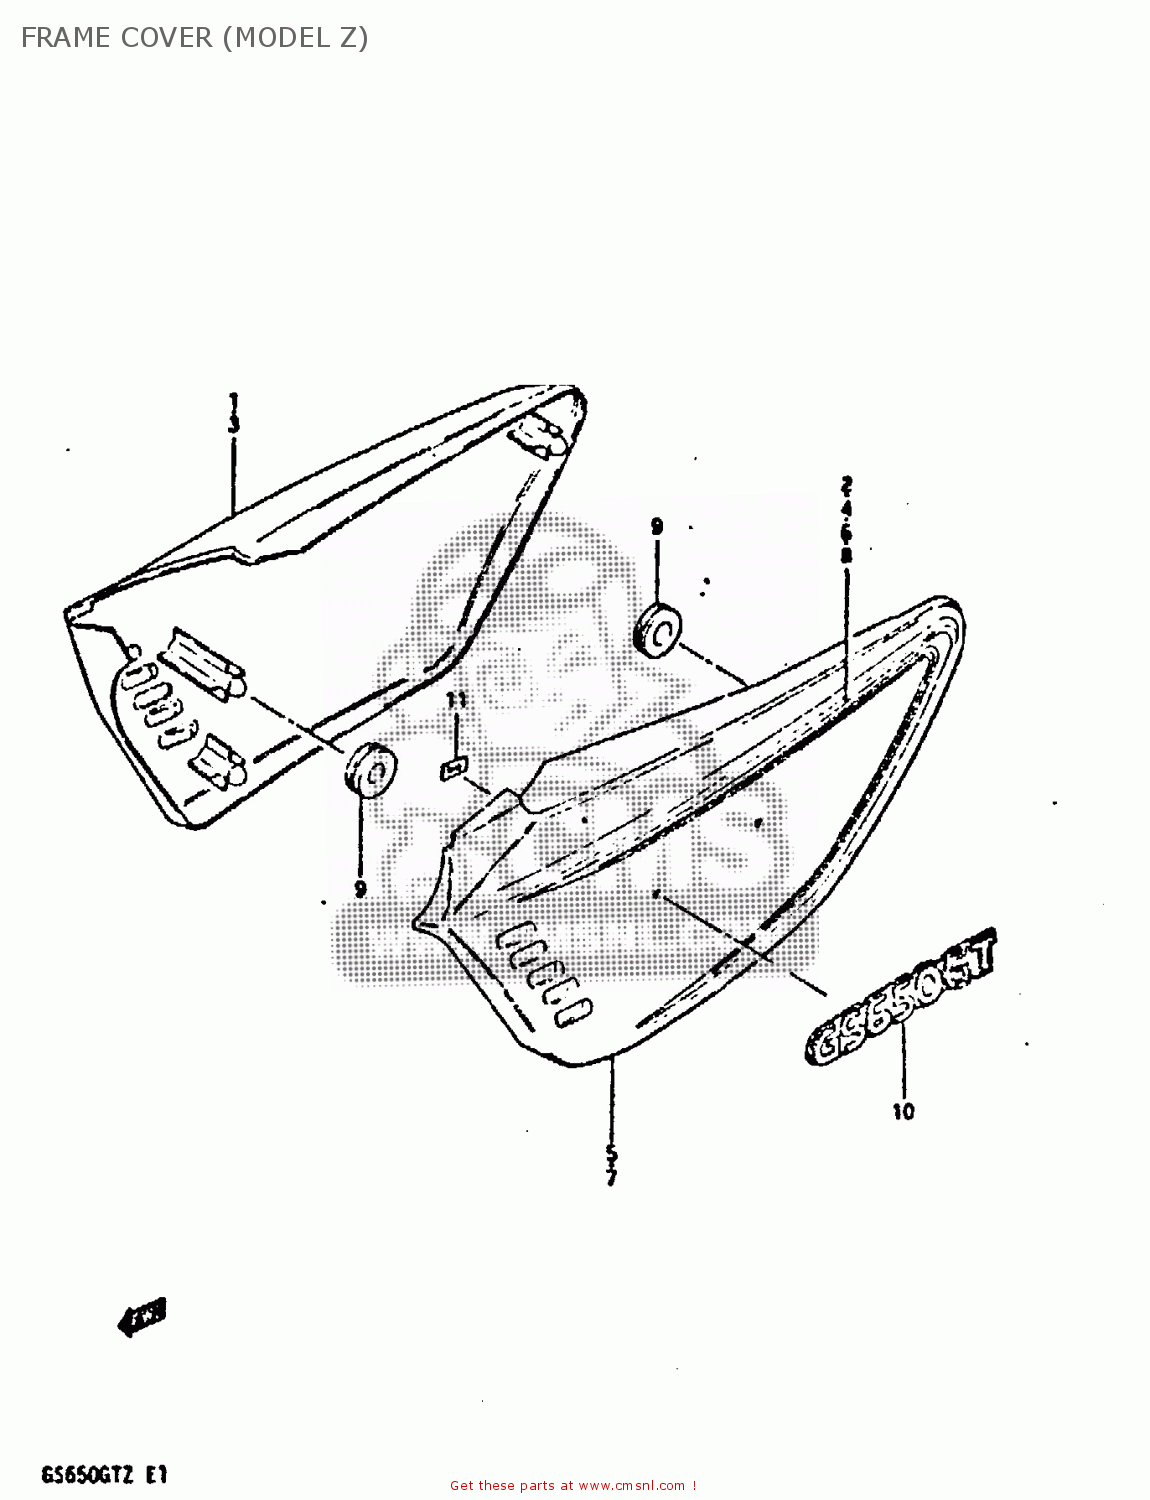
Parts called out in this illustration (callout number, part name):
1	COVER,FRAME,RIGHT
2	TAPE,FRAME COVER,RIGHT
3	COVER, FRAME RH (MAROON)
4	TAPE,FRAME COVER
5	COVER,FRAME,LEFT
6	TAPE,FRAME COVER
7	COVER, FRAME LH (MAROON)
8	TAPE,FRAME COVER
9	CUSHION
10	EMBLEM
11	NUT
